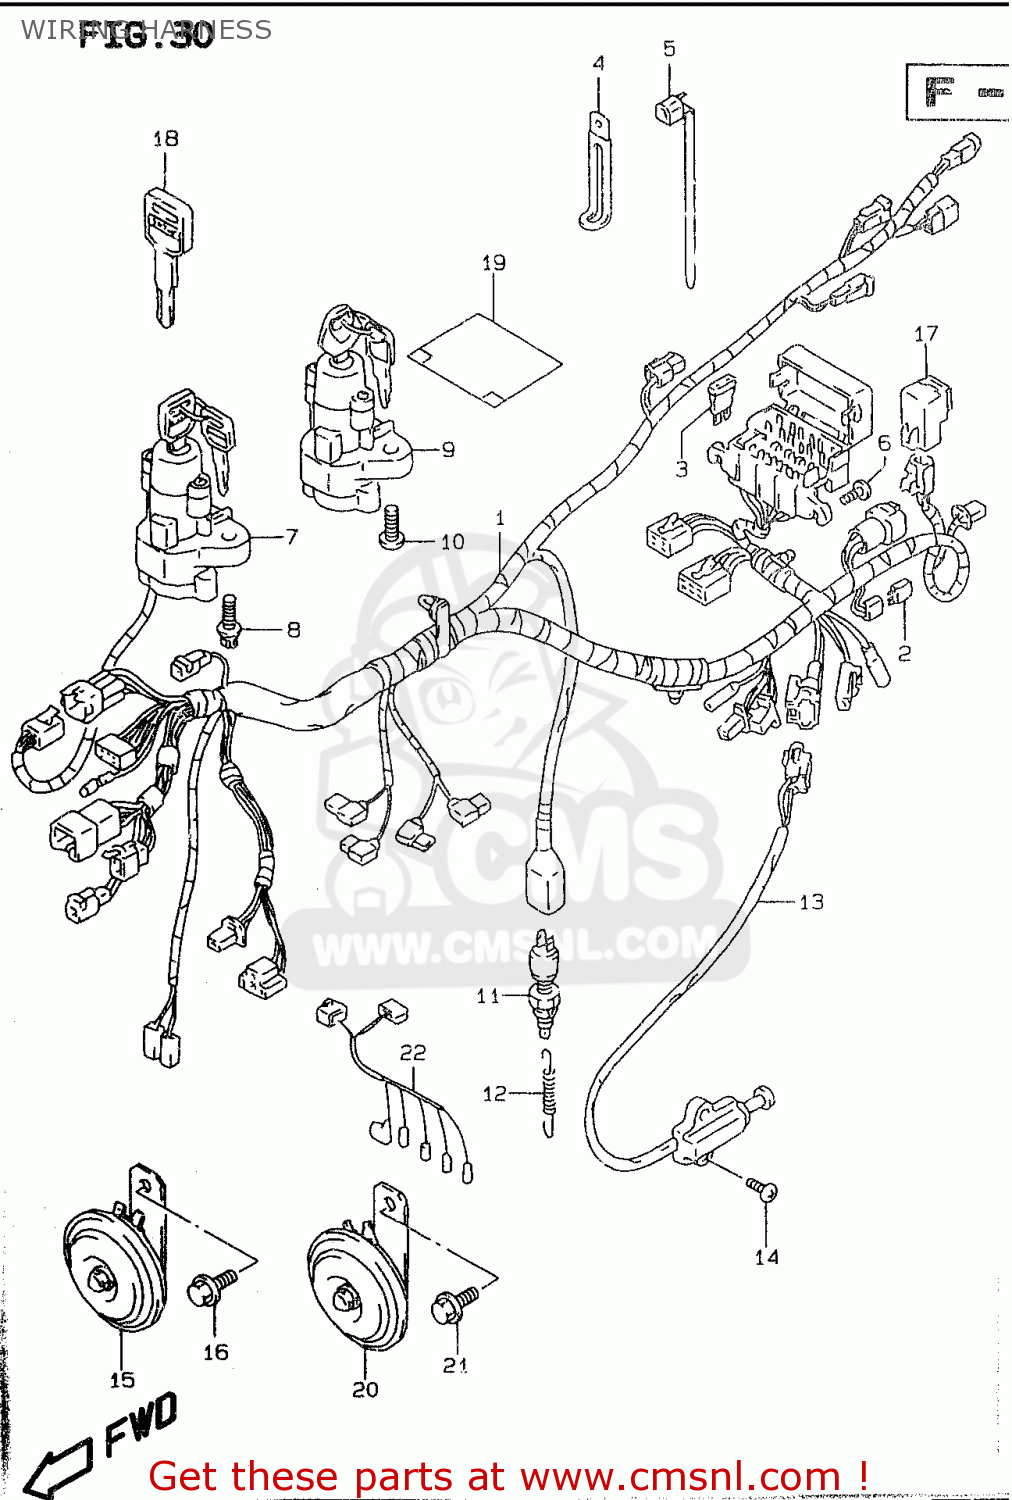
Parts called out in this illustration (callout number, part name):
1	HARNESS,WIRING
2	DIODE(STANLEY DE8804)
3	FUSE(10A)
4	CLAMP(L:65)
5	CLAMP(L:95)
6	SCREW 6X12
7	LOCK ASSY,STEERING
8	BOLT M8X20
9	LOCK ASSY,STEERING
10	BOLT(8X20)
11	SWITCH ASSY,STOP LAMP
12	SPRING
13	SWITCH ASSY,SIDE STAND
14	SCREW
15	HORN ASSY
16	BOLT
17	RELAY ASSY
18	KEY,BLANK
19	COVER,WIRING HARNESS
20	HORN ASSY
21	BOLT
22	WIRE,CARB HEATER LEAD
